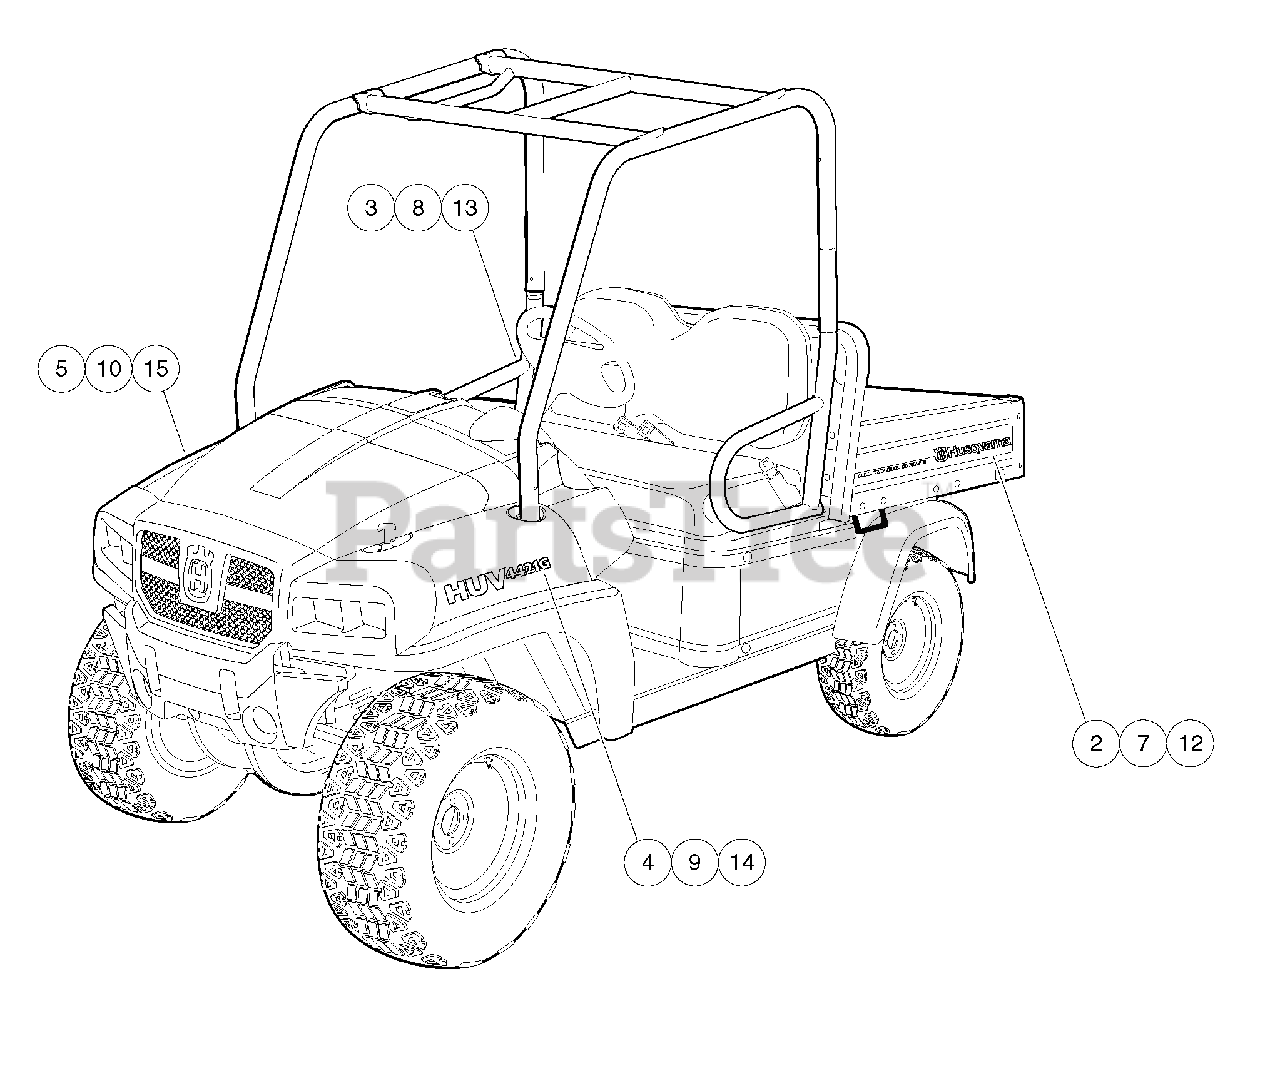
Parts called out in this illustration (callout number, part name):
1	Instl, Decal, Huv4421g,moff
2	Decal, Bed, Huv, Moff, Ds
3	Decal, Bed, Huv, Moff, Ps
4	Decal, Bct2200s, Driver-Side, Camo
5	Decal, Bct2200s, Passenger-Side, Camo
6	Instl,decal,huv4421g,orange
7	Decal, Bed, Huv, Orange, Ds
8	Decal, Bed, Huv, Orange, Ps
9	Decal, Huv 4421g, Orange, Ds
10	Decal, Huv 4421g, Orange, Ps
11	Instl,decal,huv4421g,olv Grn
12	Decal, Bed, Huv, Olv Grn, Ds
13	Decal, Bed, Huv, Olv Grn, Ps
14	Decal, Huv 4421g, Olv Grn, Ds
15	Decal, Huv 4421g, Olv Grn, Ps
